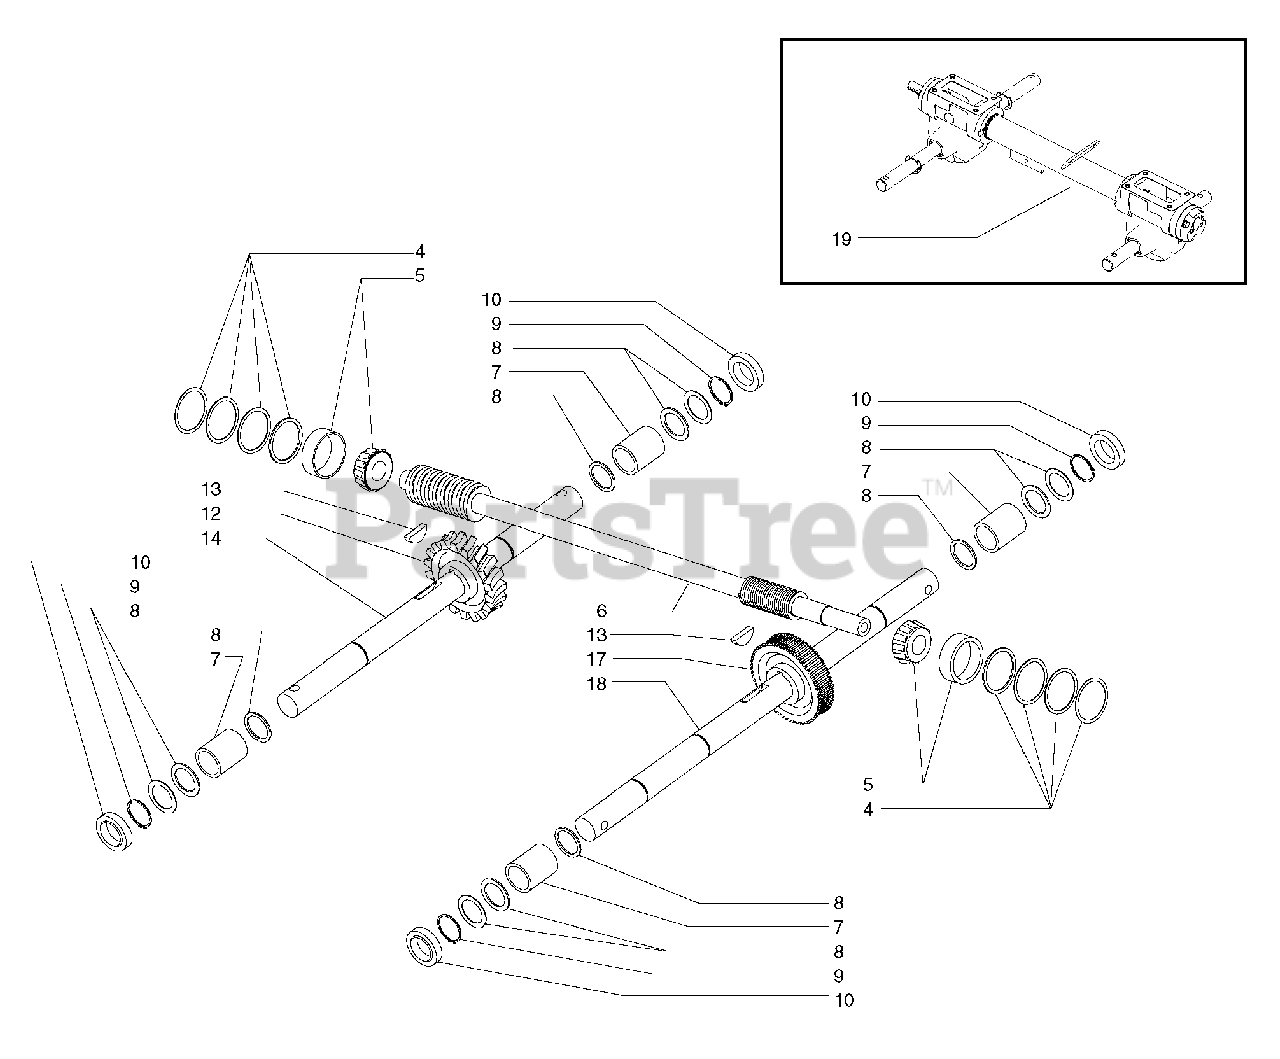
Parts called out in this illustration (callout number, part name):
4	* SHIM, Drive shaft
5	* BEARING, Tapered Roll
6	* SHAFT, Drive SRT
7	* BUSHING
8	* SPACER, 1" ID x 1-1/4 OD
9	RING, Retainer Shaft
10	SEAL, Oil, Housing
12	* GEAR, Tine, SRT
14	* SHAFT, Tine
17	* GEAR WHEEL
18	* SHAFT, WHEEL, Long
19	TRANSMISSION ASSEMBLY
